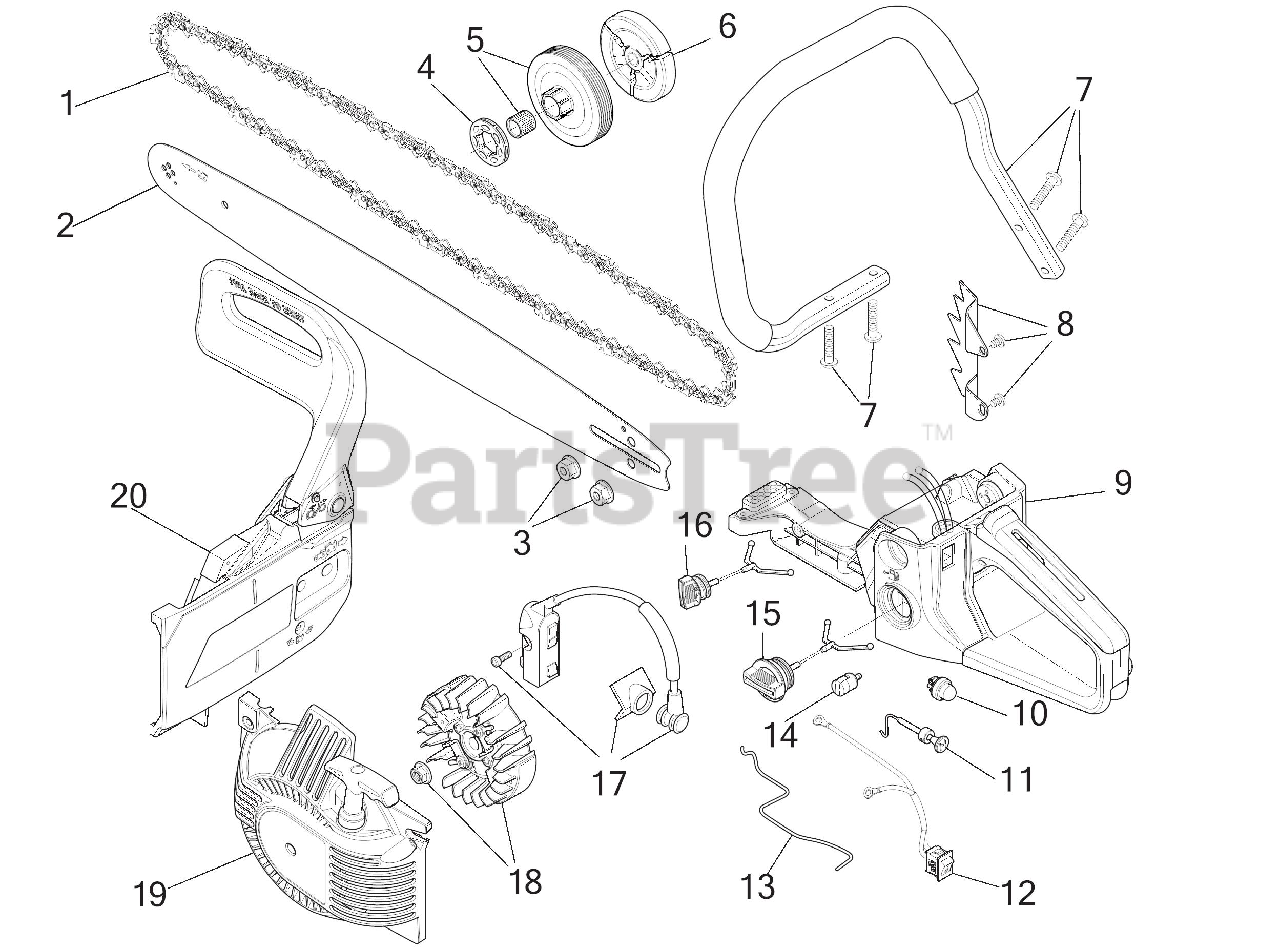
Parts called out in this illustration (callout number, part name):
1	CHAIN 18" 55C
2	BAR 18" 55CC
3	NUT:BAR:M8
4	SPROCKET
5	CLUTCH DRUM ASSEMBLY
6	CLUTCH ASSEMBLY
7	HANDLE ASSEMBLY:CHAINSA
8	SPIKE PLATE W/HDW
9	FUEL HOUSING ASSEMBLY
10	BULB:PRIMER
11	CHOKE LEVER ASSEMBLY
12	SWITCH ASSEMBLY
13	THROTTLE ROD
14	FILTER:FUEL
15	FUEL CAP ASSEMBLY
16	OIL CAP ASSEMBLY
17	MODULE:CHAINSAW
18	FLYWHEEL: CHAINSAW
19	STARTER HOUSING ASSEMBLY
20	BRAKE ASSEMBLY:CHAINSAW
